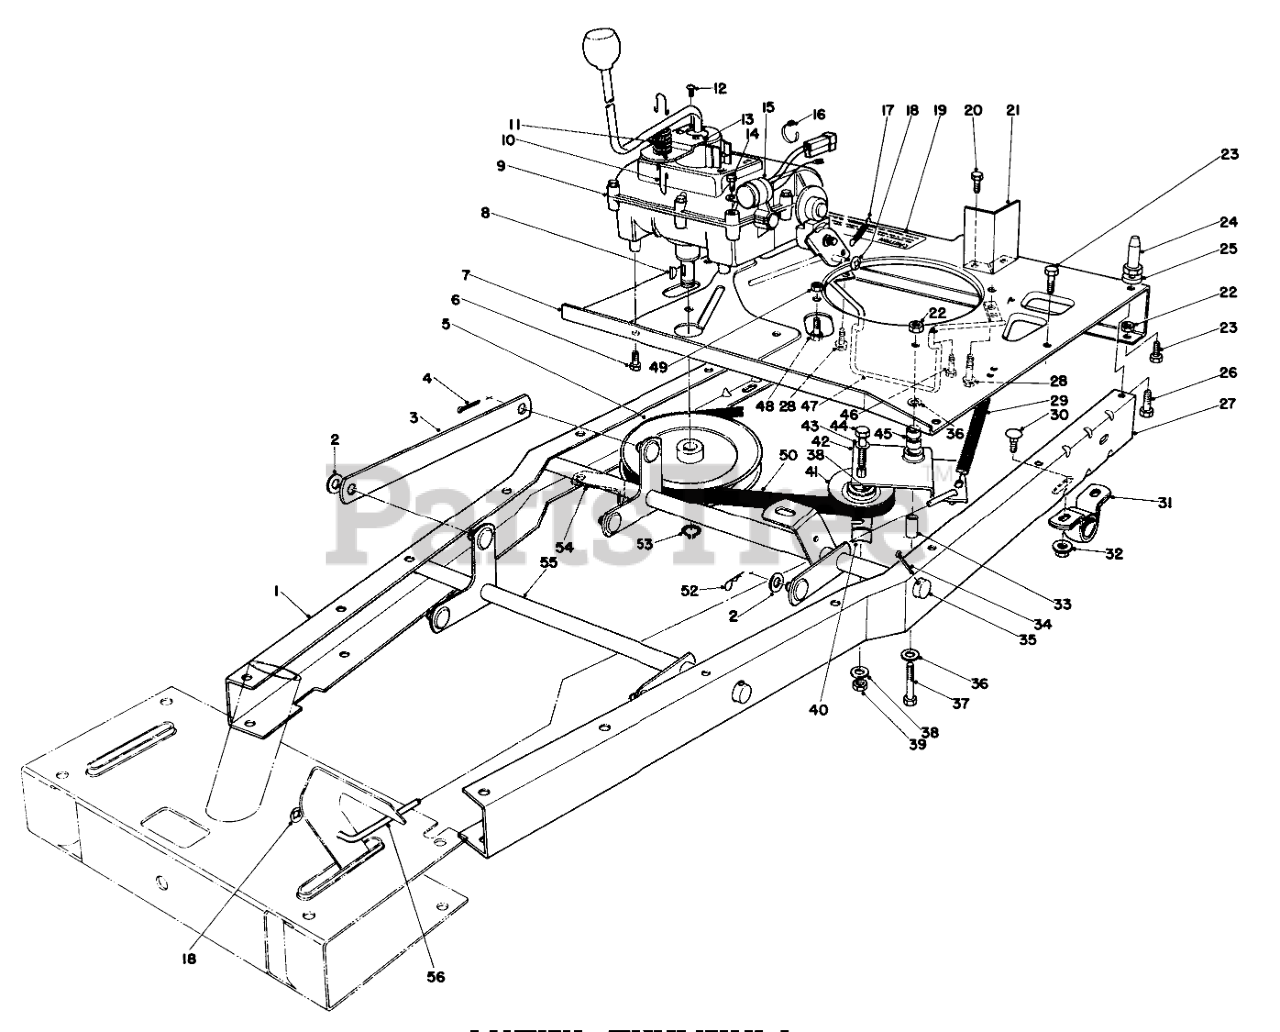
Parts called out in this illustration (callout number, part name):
1	Frame Channel R.H.
2	WASHER-FLAT
3	Linkage-Height Adj.
4	PIN-COTTER
5	PULLEY
6	5/16-18 X 5/8 SEMS SC
7	Engine Plate
8	KEY-WOODRUFF
9	Transmission
10	Neutral Spring Wire
11	SPRING
12	SCREW-HEAD, PAN
13	Neutral Bracket
15	MODULE INTERLOCK
16	TIE-CABLE
17	SPRING-RETURN, BRAKE
18	PUSH ON SPEED NUT 1/4
19	Decal
20	Hex Hd. Screw
21	Baffle-Carb
22	NUT-LOCK, CONE
23	SCREW-HH
24	PIN-MOUNTING, LOWER
25	SPACER-PIN, MOUNTING
26	SCREW-HH
27	LH FRAME CHANNEL B
28	SCREW-HWHTF
29	Clutch Tension Spring
30	SCREW-CARR
31	PILLOW BLOCK
32	NUT-HF
33	PIVOT SPACER
34	PIN-COTTER
35	HEIGHT ADJ WA (REAR)
36	WASHER-PLAIN
37	SCREW-HH
38	WASHER-FLAT
39	NUT-LOCK, SIDE
40	RETAINER-BELT
41	PULLEY-IDLER
42	Traction Idler (Incl. Ref. #45)
43	WASHER-FLAT
44	SCREW-HH
45	Bushing
46	Screw-HH
47	Belt Guide
48	SCREW-HH
49	NUT-HF
50	V-BELT
52	PIN-COTTER
53	RING-SNAP, EXTERNAL
54	TRANS BELT RET B
55	FRONT LIFT WA B
56	Clutch Rod
